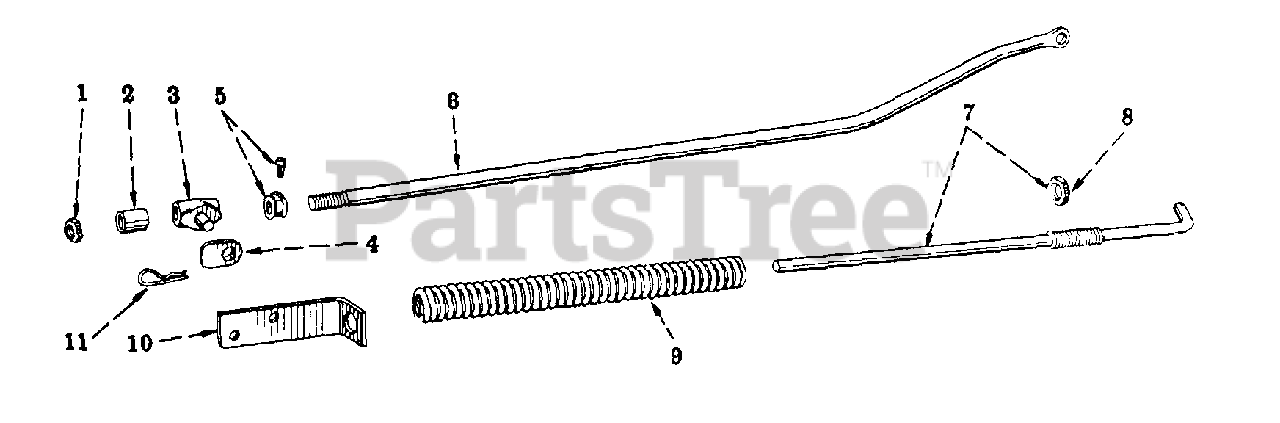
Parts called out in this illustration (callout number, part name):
1	NUT, 7/8-9 HEX. JAM
2	BUSHING, LIFT LINK
3	TRUNNION, LIFT LINK
4	BUSHING, TRUNNION
5	COLLAR W/SCREW, IH-110447, SET
6	LINK W/NUT, IH-218444, LIFT
7	ROD W/NUT, IH-218446, HELPER SPRING
8	NUT, 1-1/8-7 HEX. JAM
9	SPRING, HELPER
10	GUIDE, HELPER SPRING ROD
11	PIN, 3/16 QUICK-ATTACHABLE COT
